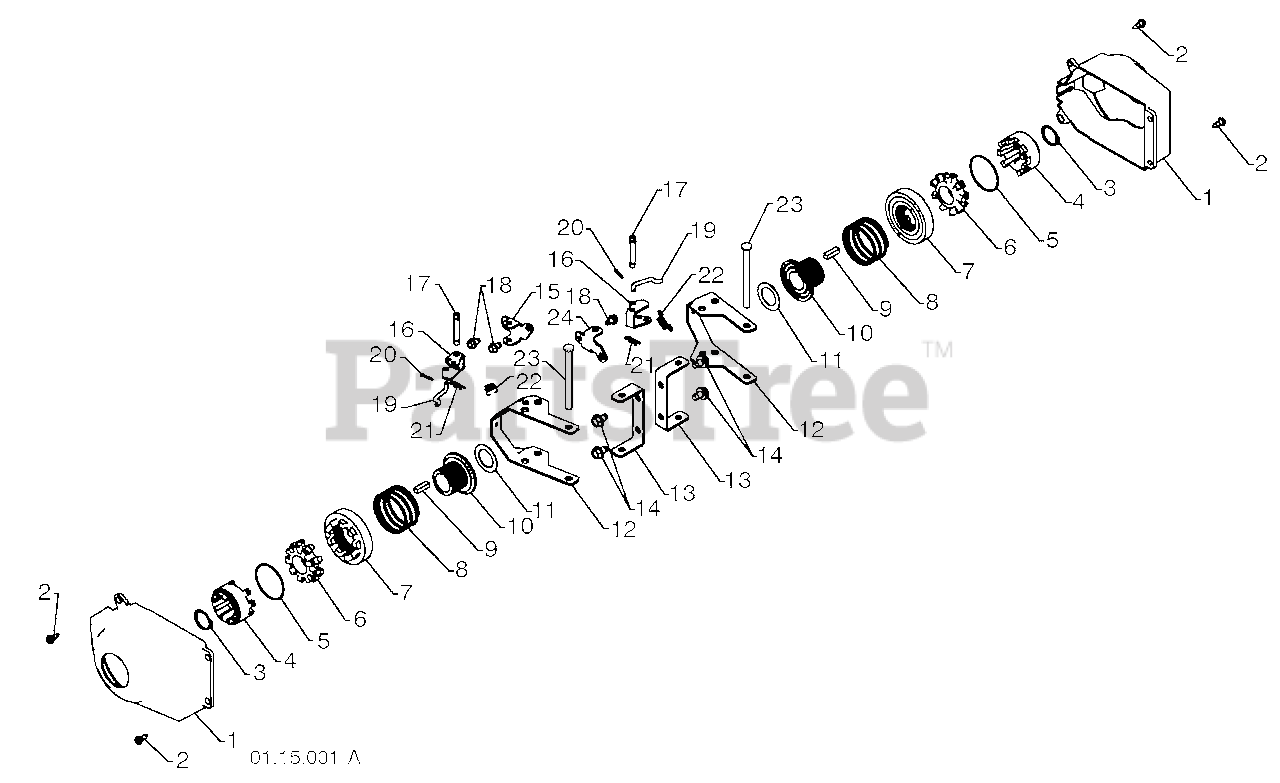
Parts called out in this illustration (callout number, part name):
1	COVER
2	SHOULDER SCREW
3	RETAINER RING
4	WHEEL DRIVER
5	RETAINER RING
6	WHEEL LOBE
7	CLUTCH SLIDE
8	SPRING
9	SQUARE KEY
11	THRUST WASHER
12	STEERING YOKE
13	STEERING BRACKET
14	SCREW 5/16-18 X .50
15	PIVOT BRACKET
16	BELLCRANK
17	BELLCRANK PIN
18	SCREW 1/4-20 X .375
19	STEERING LINK
20	RETAINER
21	RETAINER
22	SPRING
23	LEVER PIN
24	PIVOT BRACKET
